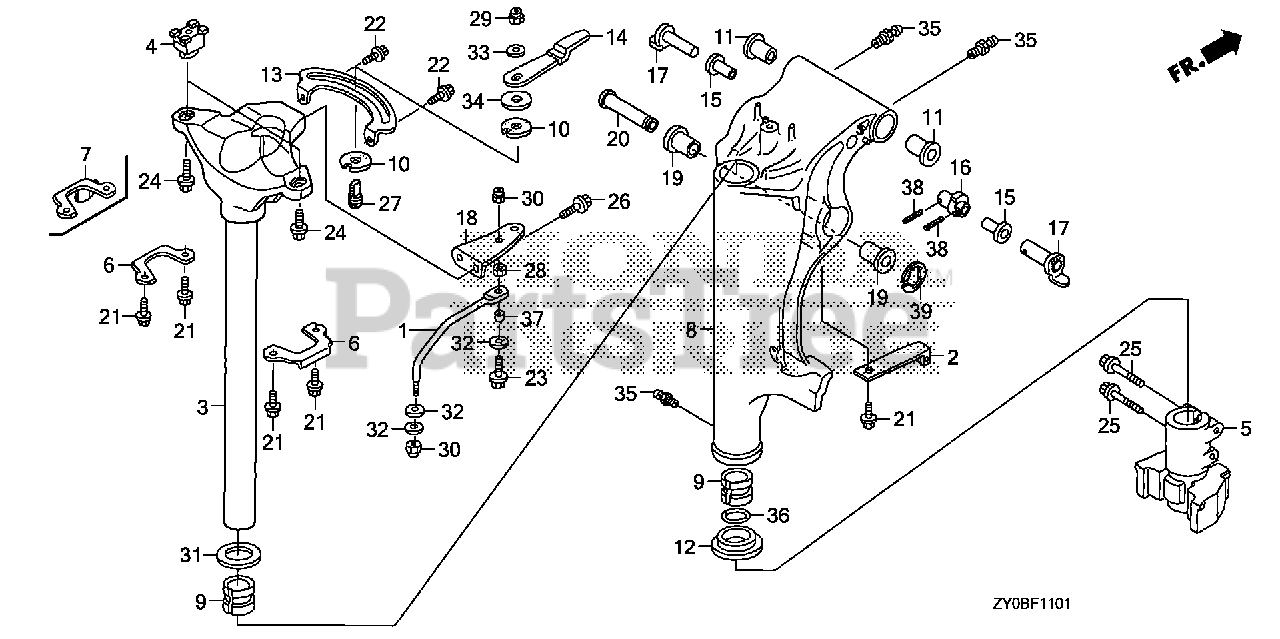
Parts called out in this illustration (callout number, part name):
1	ROD, STEERING
2	SPRING, CLICK
3	FRAME, MOUNTING (L)
4	RUBBER, MOUNTING (UPPER)
5	RUBBER, MOUNTING (LOWER)
6	COVER, MOUNTING RUBBER (UPPER)
7	COVER, MOUNTING RUBBER (UPPER) (PT)
8	CASE, SWIVEL *NH282MU* (L)(PT) (OYSTER SILVER METALLIC-U)
9	LINER, SWIVEL CASE
11	BUSH, SWIVEL CASE
12	COLLAR, SWIVEL CASE
15	BUSH, TILT ARM
16	BRACKET, TILTING
17	STOPPER, TILT
18	PLATE, STEERING
19	BUSH, CYLINDER (LOWER)
20	PIN, CYLINDER (UPPER)
21	BOLT, FLANGE (6X12)
23	BOLT (3/8-24UNF)
24	BOLT, FLANGE (10X25)
25	BOLT, FLANGE (8X45)
26	BOLT, FLANGE (10X20)
28	NUT (3/8-24UNF)
30	NUT, SELF-LOCK (3/8-24UNF)
31	WASHER, THRUST
32	WASHER (10MM)
35	NIPPLE, GREASE
36	O-RING (34X2.4)
37	COLLAR, STEERING ROD
38	PIN, SPRING (2.5X20)
39	E-RING (15MM)
